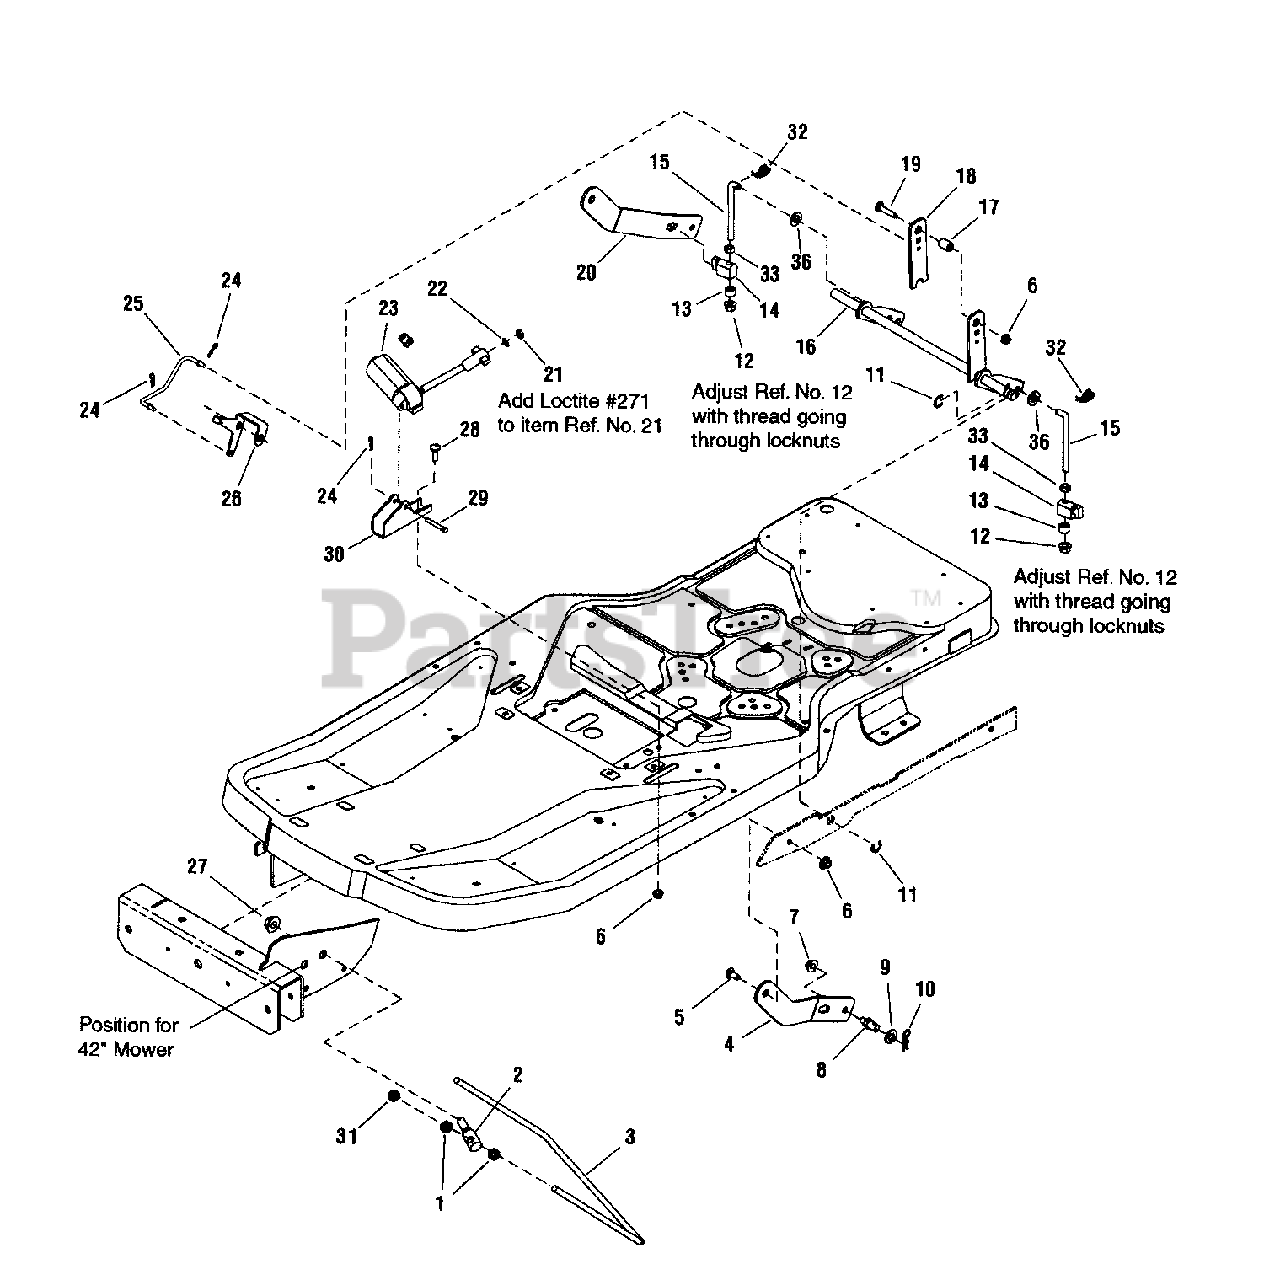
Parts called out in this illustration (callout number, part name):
1	NUT, 7/16-14 Hex Jam
2	TRUNNION, 1/2-13 Thread
3	ROD, Bail (7/16-14 Thread, 2 Places)
4	ARM, Mower Lift L.H.
5	SHOULDER BOLT, 5/16-18
6	NUT, 5/16-18 Hex Flange Lock, Small - Black
7	NUT, 3/8-16 Hex Center Lock Jam
8	PIN, 3/8-16 Threaded Shoulder
9	WASHER, 1/2" Flat (0.51 I.D. x 1.00 O.D. x .10 Thick)
10	CLIP, Hair Pin .093 Dia.
11	RING, External (Klipring) for .625 Dia. Shaft
12	NUT, 3/8-16 Hex Flange Nyloc
13	SPACER, .385 I.D. x .6697 O.D. x .455 Long, Powdered Metal
14	TRUNNION, Powdered Metal
15	ROD, Mower Lift, 3/8-16 Thread
16	WELDMENT, Lift Shaft
17	SPACER, .328 I.D. x .625 O.D. x .781 Long (Powdered metal)
18	ARM, Lift Trunnion
19	BOLT, 5/16-18 x 1-1/2" Round Head Short Square Neck, GR5
20	ARM, Mower Lift R.H.
21	NUT, 1/4-20 Hex, L.H. Thread
22	WASHER, 1/4" Flat (.27 I.D. x .62 O.D.)
23	MOTOR, Mini-Actuator (Electric)
24	HAIR PIN
25	ROD, Height-of-Cut Indicator
26	INDICATOR, Height-of-Cut
27	NUT, HEX FLANGE 1/2-13 Hex Flange Two Way Lock
28	BOLT, 5/16-18 x 1" Round Head Short Square Neck, GR5
29	PIN, Shear
30	BRACKET, Electric Motor Mount
31	NUT, 7/16-14 Hex
32	COTTER PIN, 3/8" Self-Locking, YZ
33	NUT, HEX 3/8-16 Hex
36	WASHER, .375 Flat (.41 I.D. x .87 O.D.)
